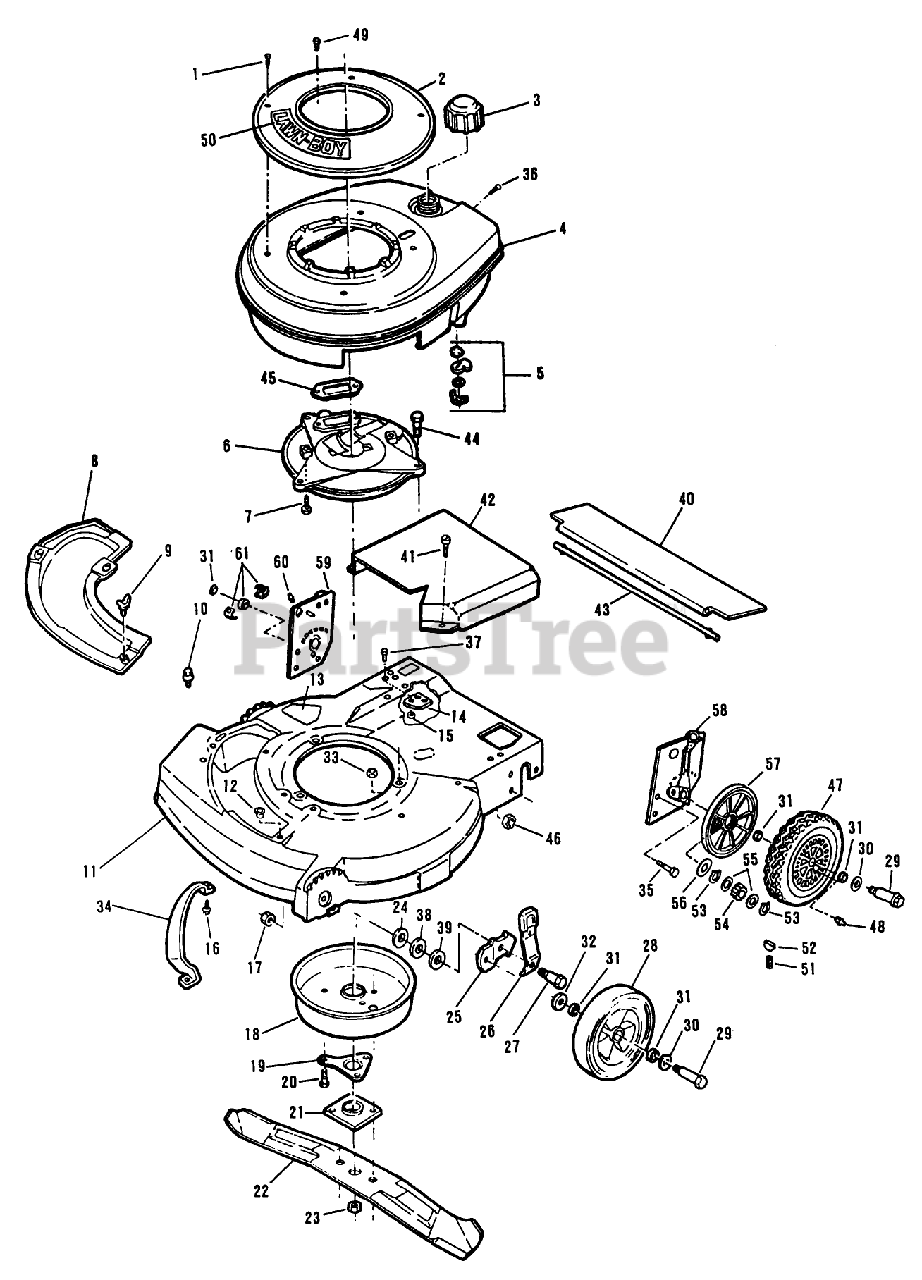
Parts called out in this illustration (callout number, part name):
1	SCREW - SELF TAPPING
3	FUEL CAP & INSERT
5	SHUT OFF VALVE KIT
6	PLATE F
7	SCREW V
9	WING SCREW LAWRE
14	BOLSTER
15	LOCKNUT E
18	MUFFLER COVER F
19	SUPPORT F
20	SCREW
21	PLATE AND COLLAR ASM
23	NUT-BLADE
24	WASHER
26	SPRING ARM ASM
27	BOLT
29	BOLT WHEEL
30	SPACER
31	WASHER
32	WASHER WROUGHT
33	NUT-LOCK F
34	BAR-TOE
36	SCREW S
38	WASHER
39	WASHER
44	SCREW-HH
46	NUT-LOCK F
48	FITTING LINCOLN
49	SCREW SEMS SM
51	SPRING
52	KEY
53	RET RING
54	PINION BROCKWAY
55	SPACER/GR ALGHNY
60	REAR AXLE BEARING
61	**FITTING LINCOLN
